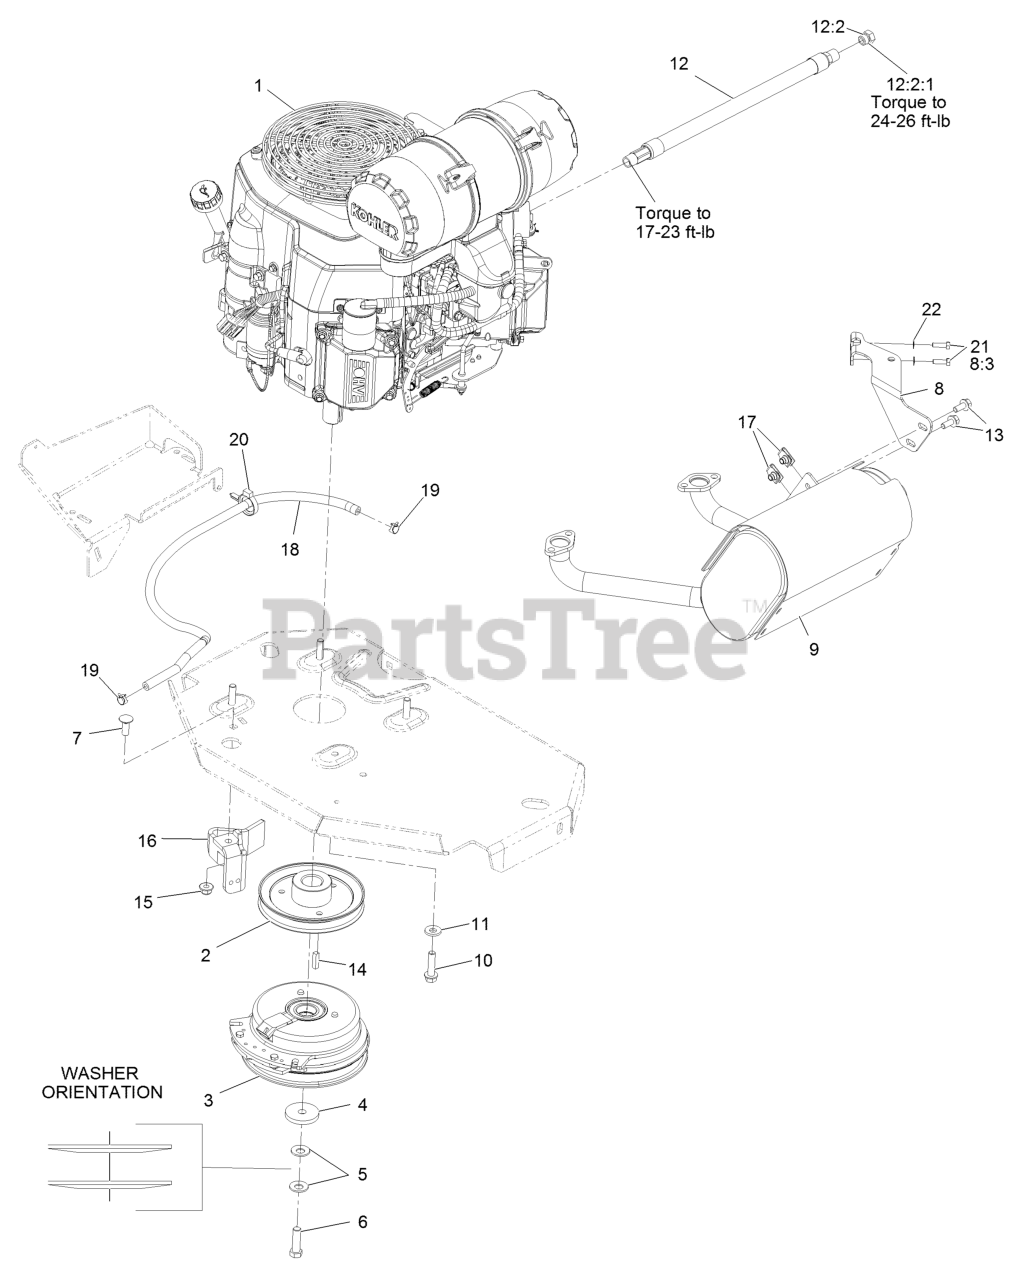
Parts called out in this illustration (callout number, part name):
2	SHEAVE
3	CLUTCH KIT
4	WASHER-CLUTCH
5	WASHER-SPRING
6	SCREW-HH 7/16-20 X 1 1/2 W/LOCTITE
7	SCREW-CARR
8	MUFFLER BRACKET KIT
8:3	SCREW-HH M6-1 X 20Mm W/Patch
10	SCREW-HWH
11	WASHER-BELLEVILLE
12	OIL DRAIN HOSE ASM
12:2	PLUG-HH
12:2:1	O-RING
13	SCREW-HHF
15	NUT-HF, NI
16	CLUTCH-ANCHOR
18	HOSE-FUEL
19	CLAMP-HOSE
20	CLAMP-HOSE
21	SCREW-HH M6-1 X 20Mm W/Patch
22	WASHER-SPRING
